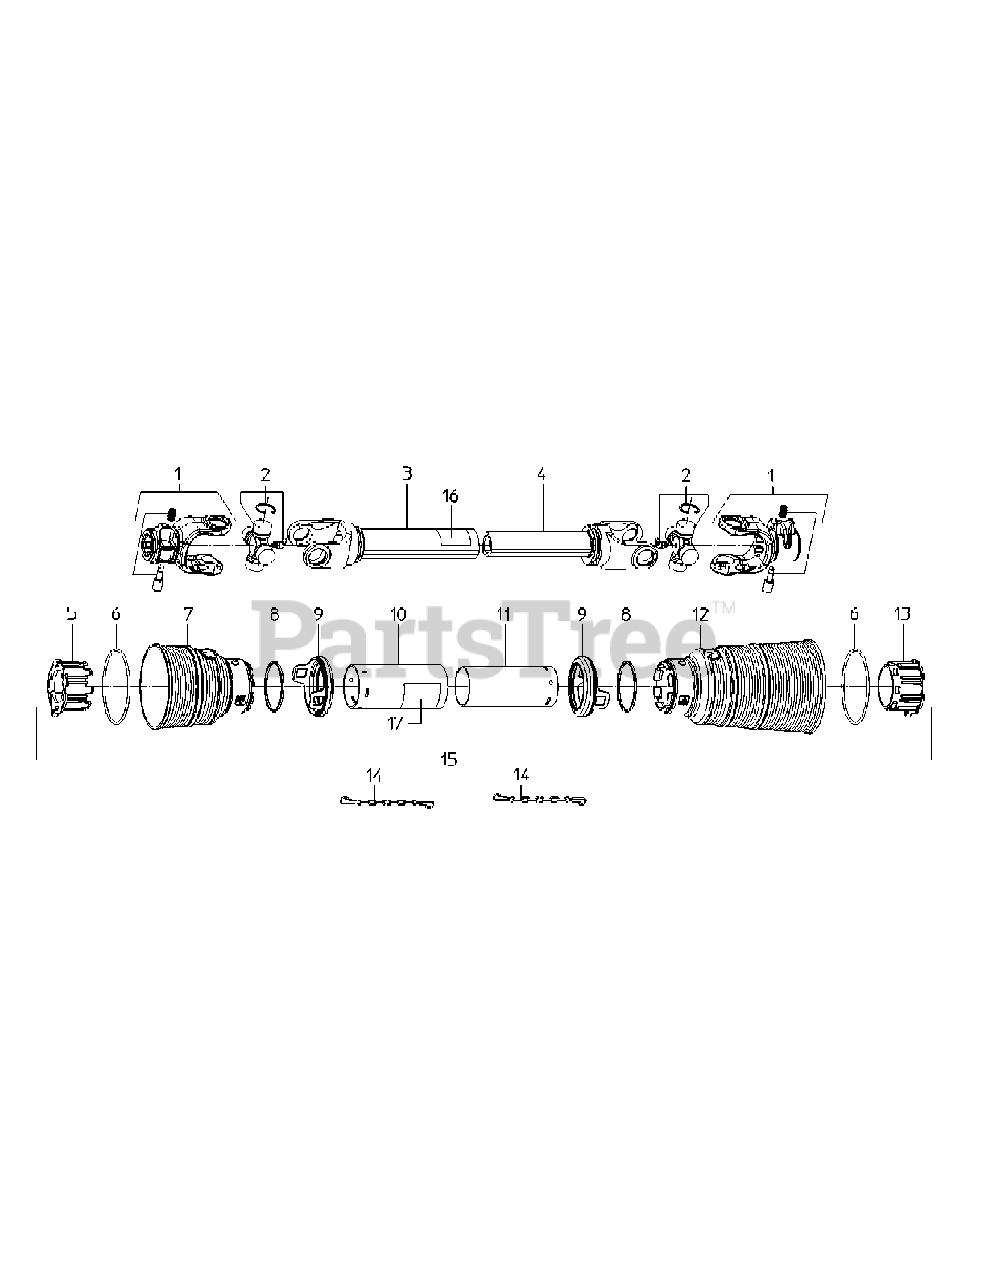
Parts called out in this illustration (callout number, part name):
2	Cross and bearing
3	Outer tube FM48
3	Outer tube FM60
3	Outer tube FM72
4	Inner tube FM48
4	Inner tube FM60
4	Inner tube FM72
5	Outer tube bearing; # 1A169161 & above
6	Stiffening ring; # 1A169161 & above
7	Outer cone (short, tractor end); # 1A169161 & above
8	Safety ring; #1A169161 & above
9	Safety sleeve; #1A169161 & above
10	Female tube shield FM48; # 1A169161 & above
10	Female tube shield FM60; # 1A169161 & above
10	Female tube shield FM72; # 1A169161 & above
11	Male tube shield FM48; # 1A169161 & above
11	Male tube shield FM60; # 1A169161 & above
11	Male tube shield FM72; # 1A169161 & above
12	Outer cone (long, implement end); # 1A169161 & above
13	Inner tube bearing; # 1A169161 & above
14	Chain
15	Complete shielding FM48
15	Complete shielding FM60
15	Complete shielding FM72
16	Decal "DANGER - Guard missing, do not operate" outer tube
17	Decal "DANGER - Rotating driveline, keep away" outer shield
